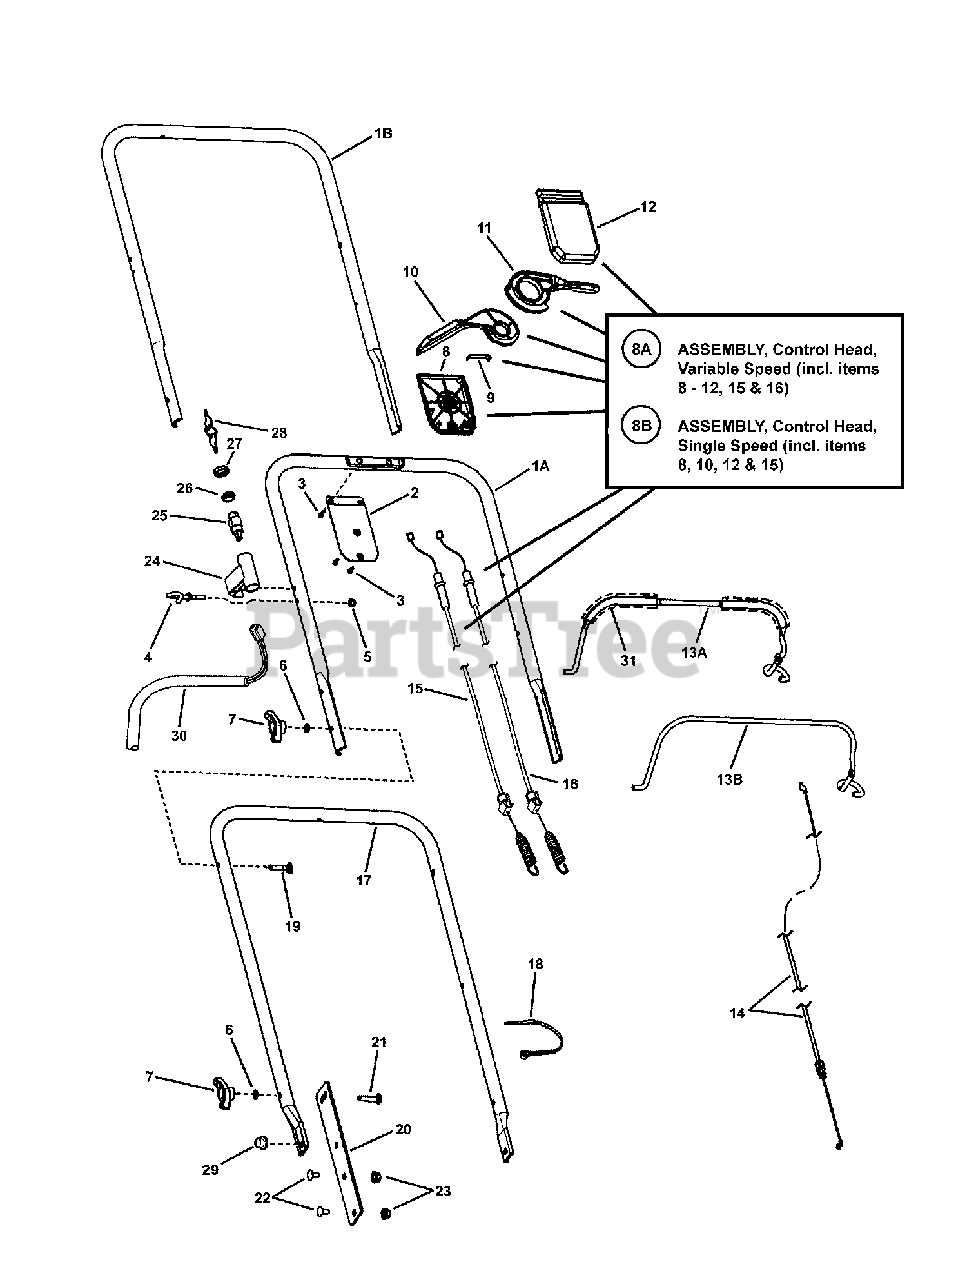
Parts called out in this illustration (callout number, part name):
1A	HANDLE, Upper, Flat
1B	HANDLE, Upper, 22" Push
2	* PLATE, Control Panel
3	* SCREW, #8-16 Recessed Pan Head (Torxplus)
4	GUIDE, Rope
5	NUT, 1/4-20 Hex Nyloc
6	WASHER, 5/16 Internal Tooth Lock
7	KNOB, 5/16-18 Wing (Black)
8	* CASE HALF, Bottom, Black
8A	ASS'Y, Control Head, Variable Speed (Incl. items 8-12, 15 & 16)
8B	ASS'Y, Control Head, Single Speed (Incl. items 8, 10, 12 & 15)
9	** SPRING STEEL
10	* CLUTCH LEVER, Silver
11	** ASS'Y., Speed Lever/Friction Material (Snapper)
12	* CASE HALF, Top, Variable Speed- Black
12	* CASE HALF, Top, Single Speed- Black
13A	BAIL, Brake (self-propelled mower)
13B	BAIL, 22" (push-mower)
14	CABLE, Zone Control
15	* CABLE, Clutch
16	** CABLE, Speed
17	HANDLE, Lower
18	WIRE TIE, 11 Inch Black Nylon
19	BOLT, 5/16-18 x 2" Curved Head Square Neck GR 2
20	BRACKET, Lower Handle, Black Textured
21	BOLT, Carriage 5/16-18 x 1-1/2", GR 5
22	BOLT, Carriage 5/16-18 x 5/8", GR 5
23	NUT, 5/16-18 Hex Flange Lock, GR 5
24	HOUSING, Snap-On E-Start
25	SWITCH, Electric Start (Start/Run)
26	NUT, 5/8-32 E-Start
27	CAP, E-Start
28	KEY, Ignition (Pair)
29	PUSHNUT, 3/8"
30	WIRING HARNESS, B&S
31	FOAM GRIP, 7"
